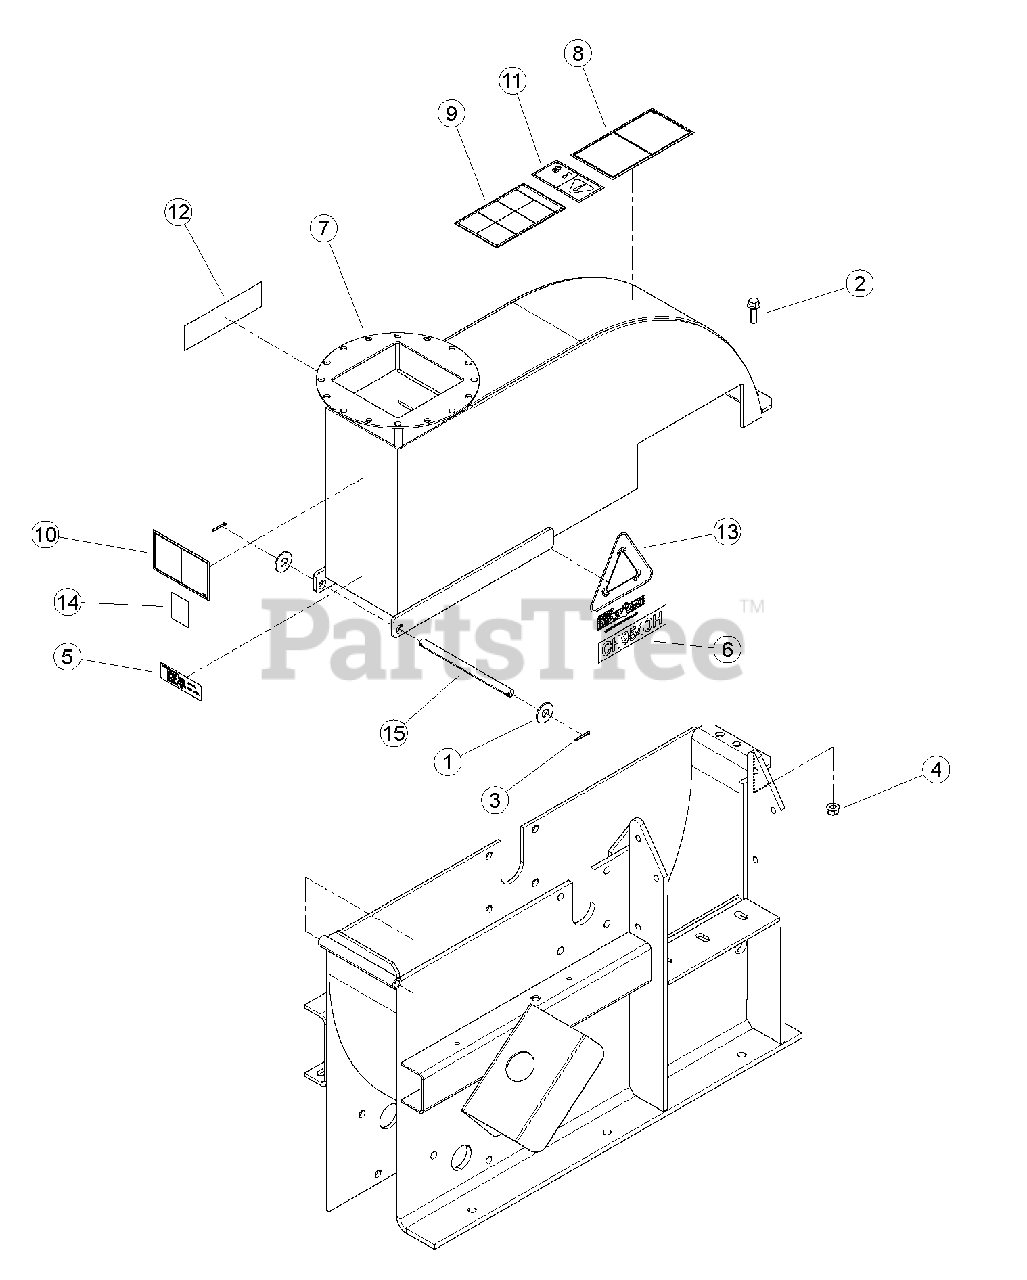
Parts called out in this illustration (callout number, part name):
1	WASHER, 1/2" FLAT ZP
2	BOLT, 3/8 X 1-1/4 FLANGE NC
3	PIN, 1/8 X 1.00 ZP COTTER
4	NUT, 3/8-16 NYLOCK FLANGE
5	DECAL, ATLANTIC BRIDGE LTD INFO (CE COMPLIANT ONLY)
6	DECAL, MODEL CH9540H
6	DECAL, MODEL CHF9540H
7	ASSEMBLY, CHIPPER COVER W/ DECALS
8	DECAL, KNIFE ACCESS ISO
9	DECAL, OPERATING INSTRUCTIONS ISO
10	DECAL, DISCHARGE ISO
11	DECAL, MAINTENANCE ISO
12	DECAL, ECHO BEARCAT 6.82 X 1.90
13	DECAL, CHIP IT
14	DECAL, ECHO BEARCAT QR CODE
15	SHAFT, CHIPPER TOP PIVOT
